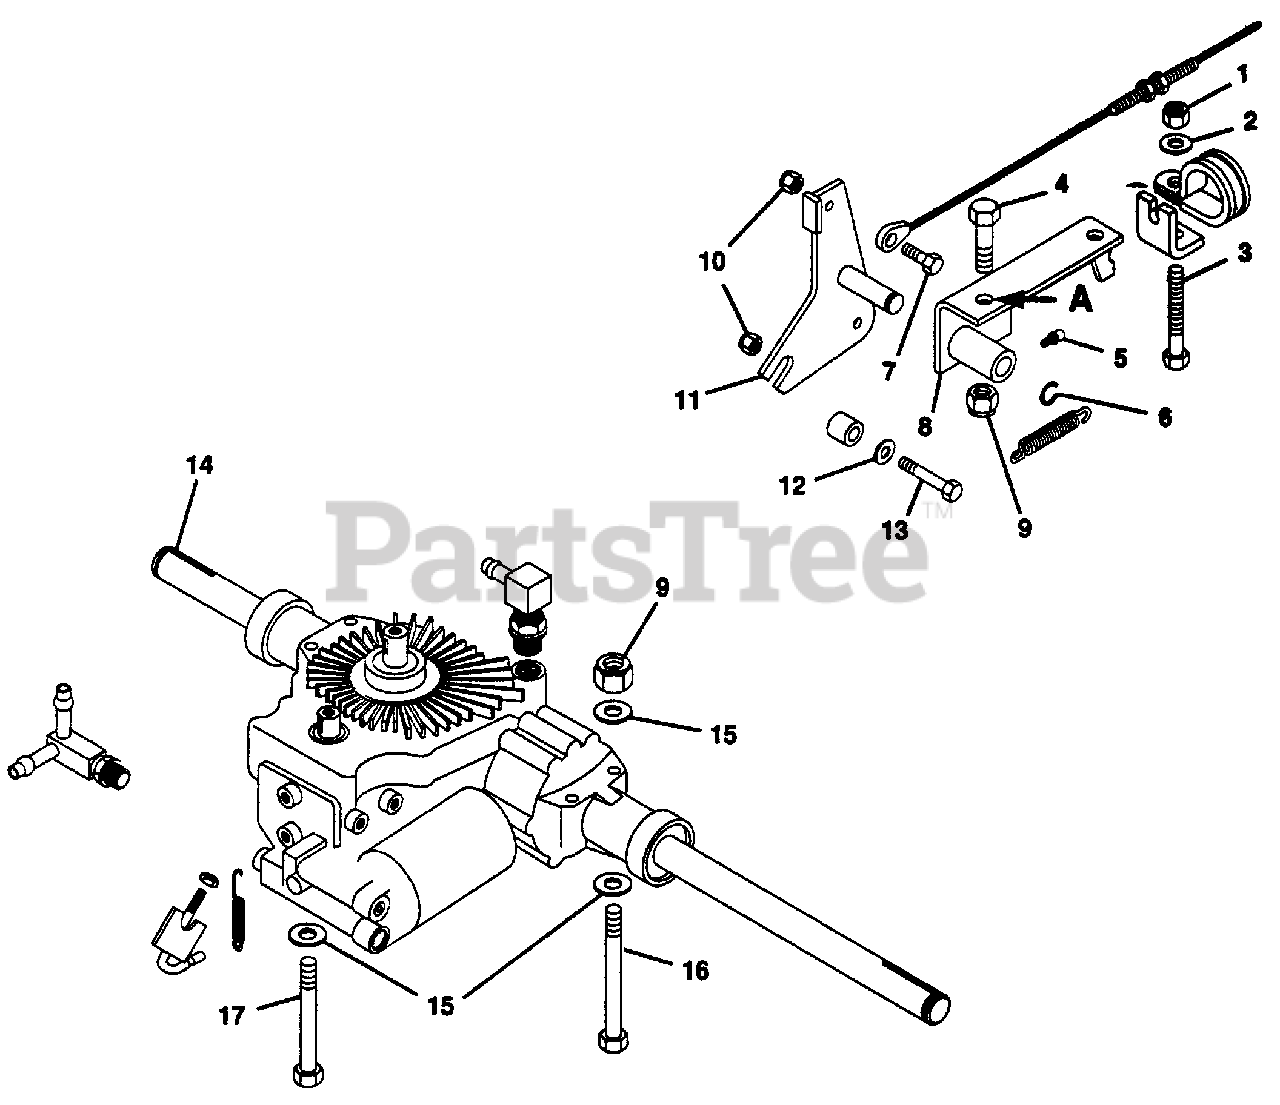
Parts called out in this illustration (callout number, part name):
1	Nut, Lock 5/16-18
2	Washer, Flat .344x.688x.065
3	Bolt, Hex 5/16-18x1.00
4	Bolt, Hex 3/8-16x1.00
5	Fitting, Lube 1/4-28
6	E-Ring, 5133-50
7	Bolt, Hex 1/4-20x.875
8	Weldment, Brake Pivot
9	Nut, Lock 3/8-16
10	Nut, Lock 1/4-20
11	Weldment, Brake Arm
12	Washer, Flat .281x.625x.065
13	Bolt, Hex 1/4-20x1.75
14	Transaxle, Hydrostatic
15	Washer, Flat .406x.812x.065
16	Bolt, Hex 3/8-16x4.00
17	Bolt, Hex 3/8-16x3.25
